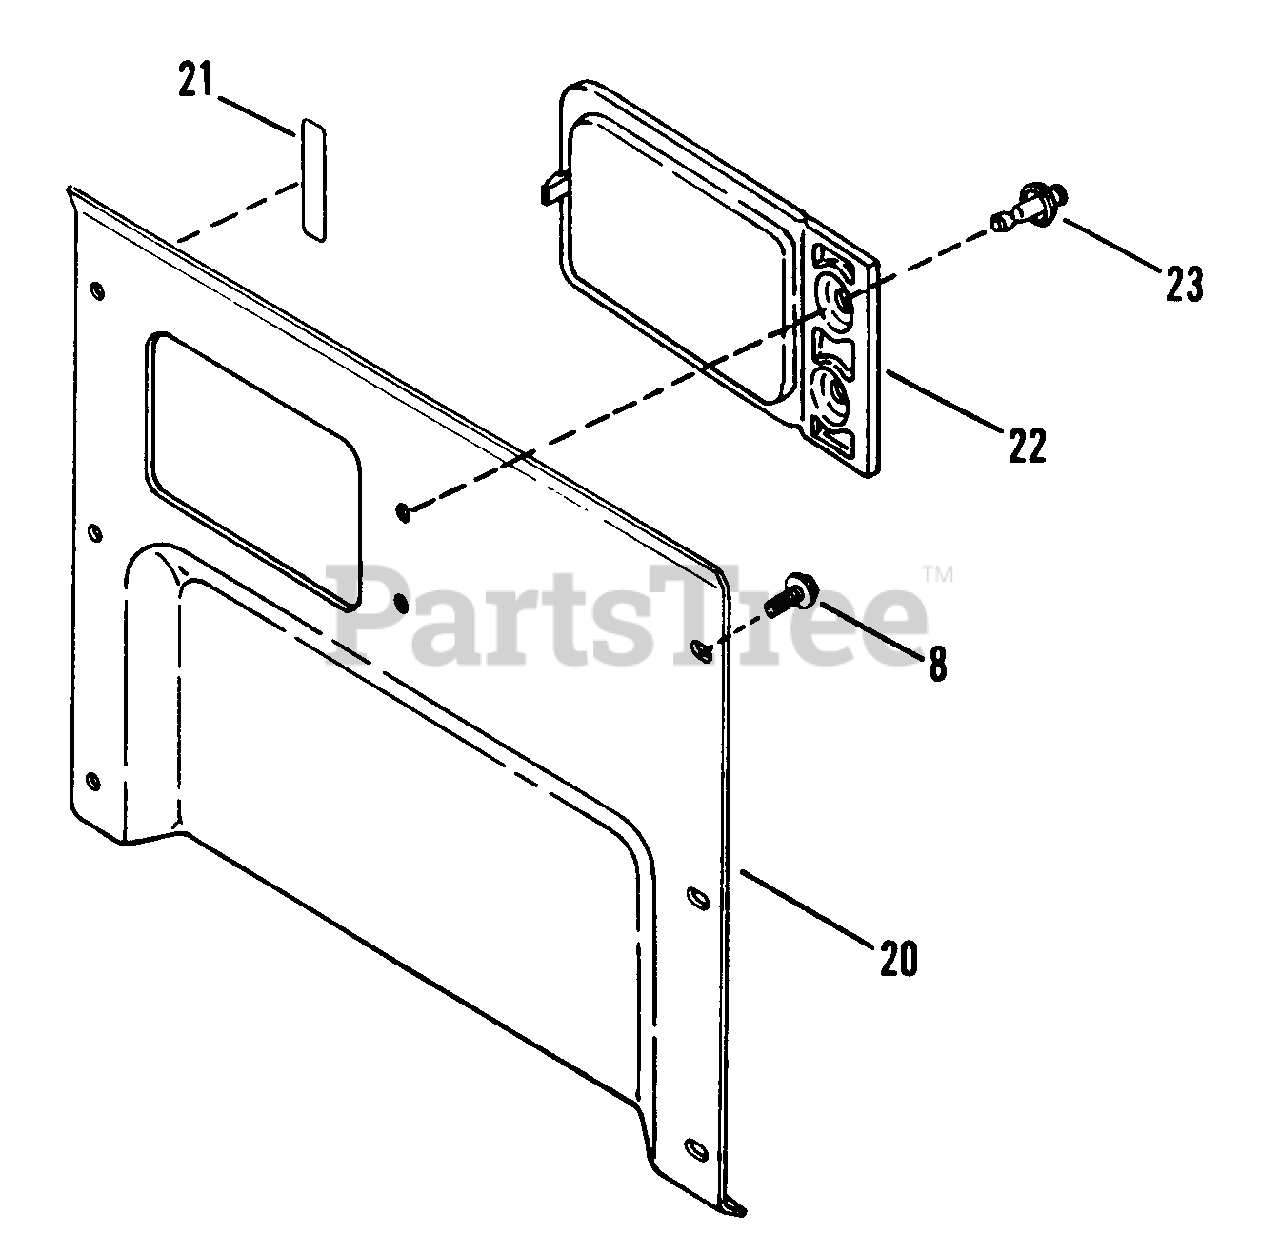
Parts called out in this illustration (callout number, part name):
8	SCREW, 5/16-18 x 5/8" Self-Tapping
20	COVER, Rear
21	DECAL, Roll
22	COVER, Transmission Oil Access (No longer available)
23	SCREW, Expansion
